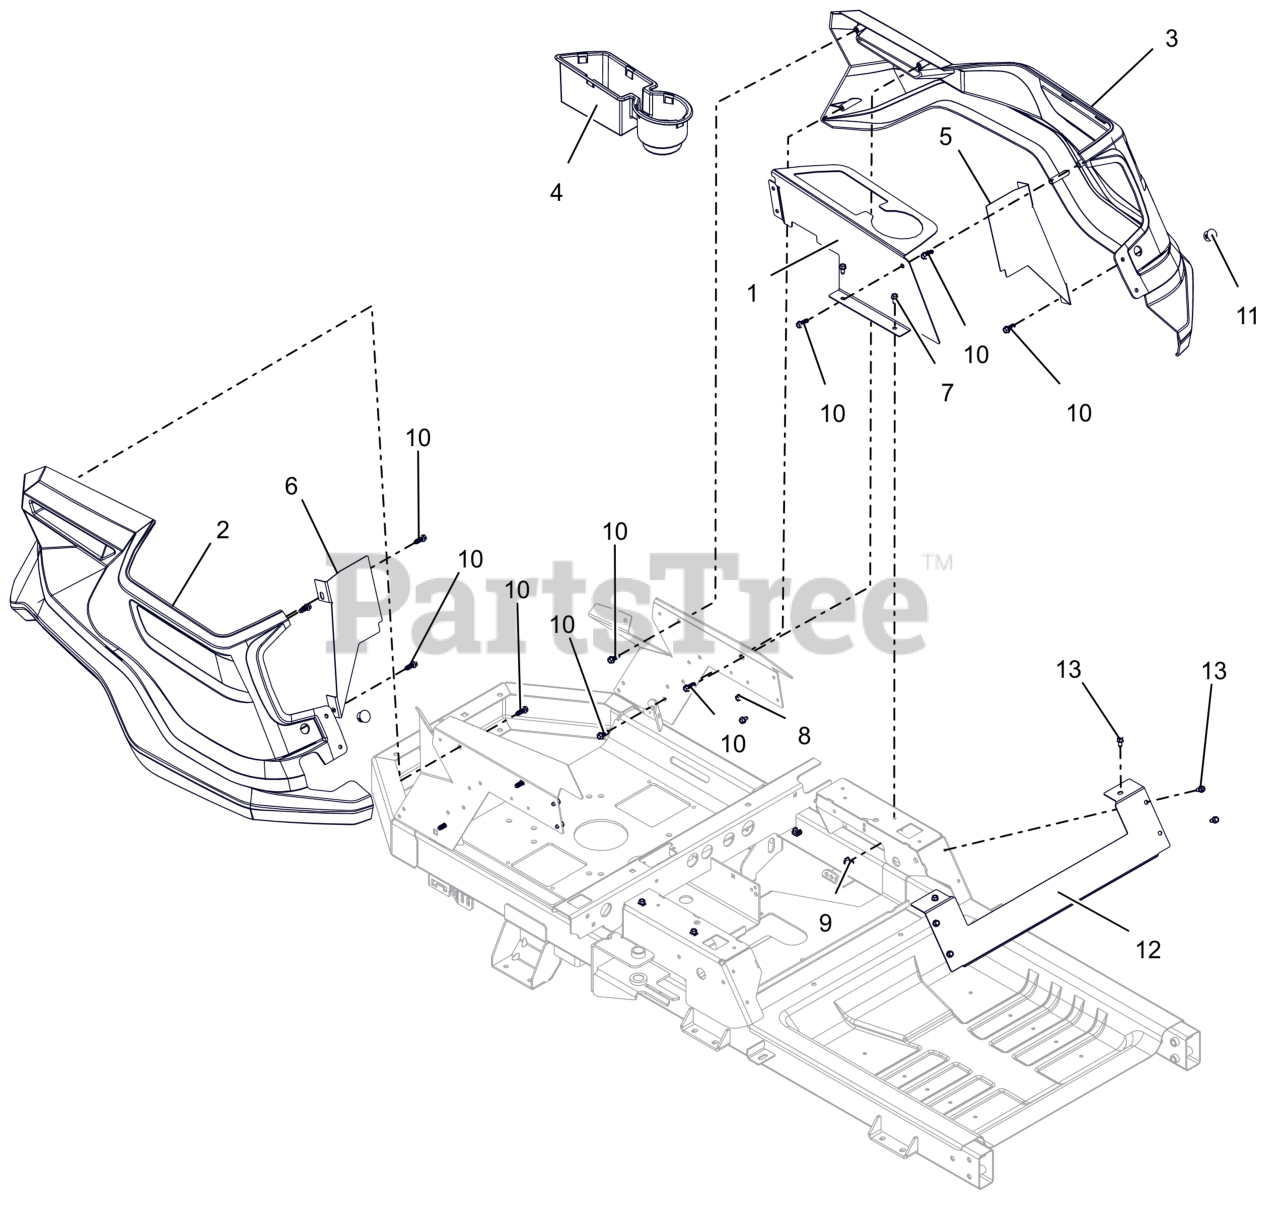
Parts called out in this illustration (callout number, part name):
1	PANEL, LEFT SIDE FENDER MOUNT
2	FENDER, RH IKON
3	FENDER, LH IKON
4	INSERT, CUP/STORAGE HOLDER
5	PLATE, LH BLOCKER
6	PLATE, RH BLOCKER
7	SCR-TAP .25-20X.50 HWH ZCC
8	SCR,TAP .25-20X.375 HWH TR ZCC
9	NUT RETNR .25-20
10	SCR-.312X.75 #14H H/W/H H/L CZ
11	PLUG, HOLE .75 (BLACK)
12	PLATE, SEAT KICK
13	SCR-TAP .25-20X.50 HWH ZCC
